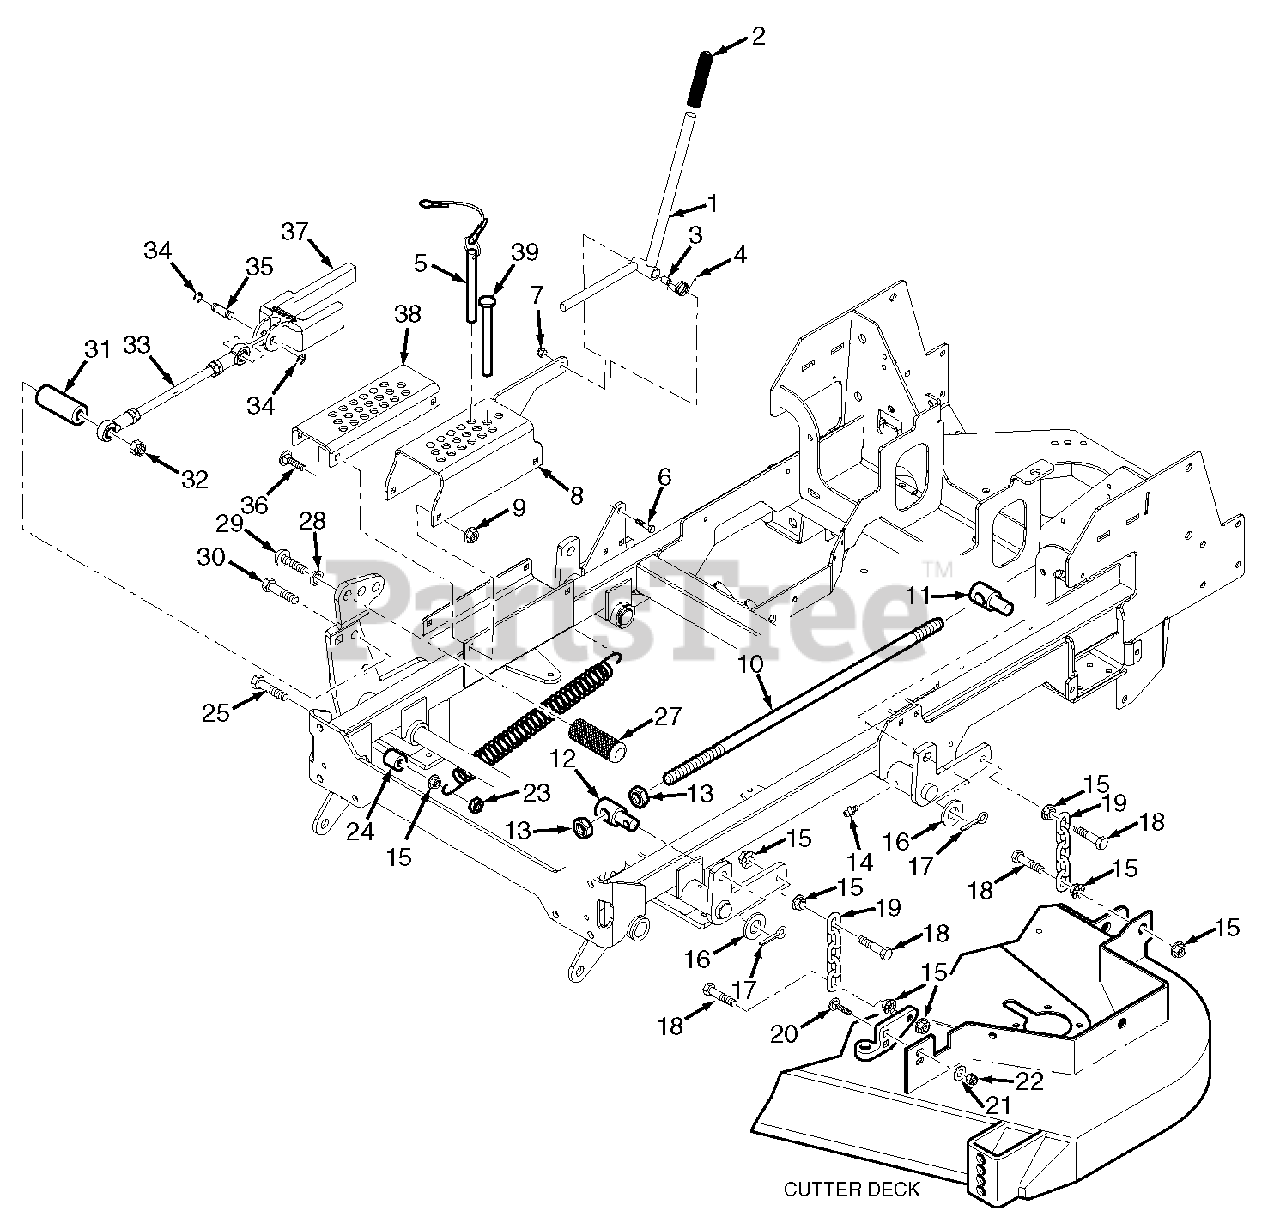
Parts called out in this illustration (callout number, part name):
1	Deck Latch Assembly
2	Grip, Deck Latch
3	Spacer, Deck Latch
4	Spring, Torsion - Lever Return
5	Pin Assembly, w/Lanyard
6	Bolt, Hex Head 3/8-16 x 3"
7	Nut, Elastic Stop 3/8-16
8	Adjustment Bracket, Cutting Height
9	Nut, Serrated Flange 5/16-18
10	Stud, 1/2-13 x 20"
11	Swivel Joint, LH
12	Swivel Joint, RH
13	Nut, 1/2-13
14	Grease Fitting, 1/4-28 Self Tap
15	Nut, Serrated Flange 3/8-16
16	Flatwasher, 5/8-.656 x 1.312 x .095
17	Cotter Pin, 3/16 x 1"
18	Bolt, Hex Head 3/8-16 x 1-1/2"
19	Chain
20	Bolt, Carriage 7/16-14 x 1-1/4"
21	Flatwasher, 1/2-.531 x 1.062 x .095
22	Nut, Elastic Stop 7/16-11
23	Nut, Center Lock 3/8-16
24	Spacer
25	Bolt, Hex Head 3/8-16 x 1-1/4"
26	Spring, Helper
27	Foot Pedal, Height Adjustment
28	Lockwasher, 5/8" Spring
29	Capscrew, 5/8-11 x 1-1/2"
30	Bolt, Hex Head 1/2-13 x 4"
31	Spacer, Deck Lift Pedal
32	Nut, Elastic Stop 1/2-13
33	Linkage Assembly, Deck Lift
33	Rod, Deck Lift
33	Jam Nut, 1/2-20 LH Thread
33	Rod End, 1/2-20 LH Female
33	Jam Nut, 1/2-20 RH Thread
33	Rod End, 1/2-20 RH Female
34	Retaining Ring, 1/2" Ext. "E"
35	Pin, Deck Lift
36	Bolt, Hex Head 5/16-18 x 1"
36	Lockwasher, 5/16" Spring
37	Slide, Height Adjust
38	Adjustment Bracket, Lower Cut Height
39	Pin, Locking
